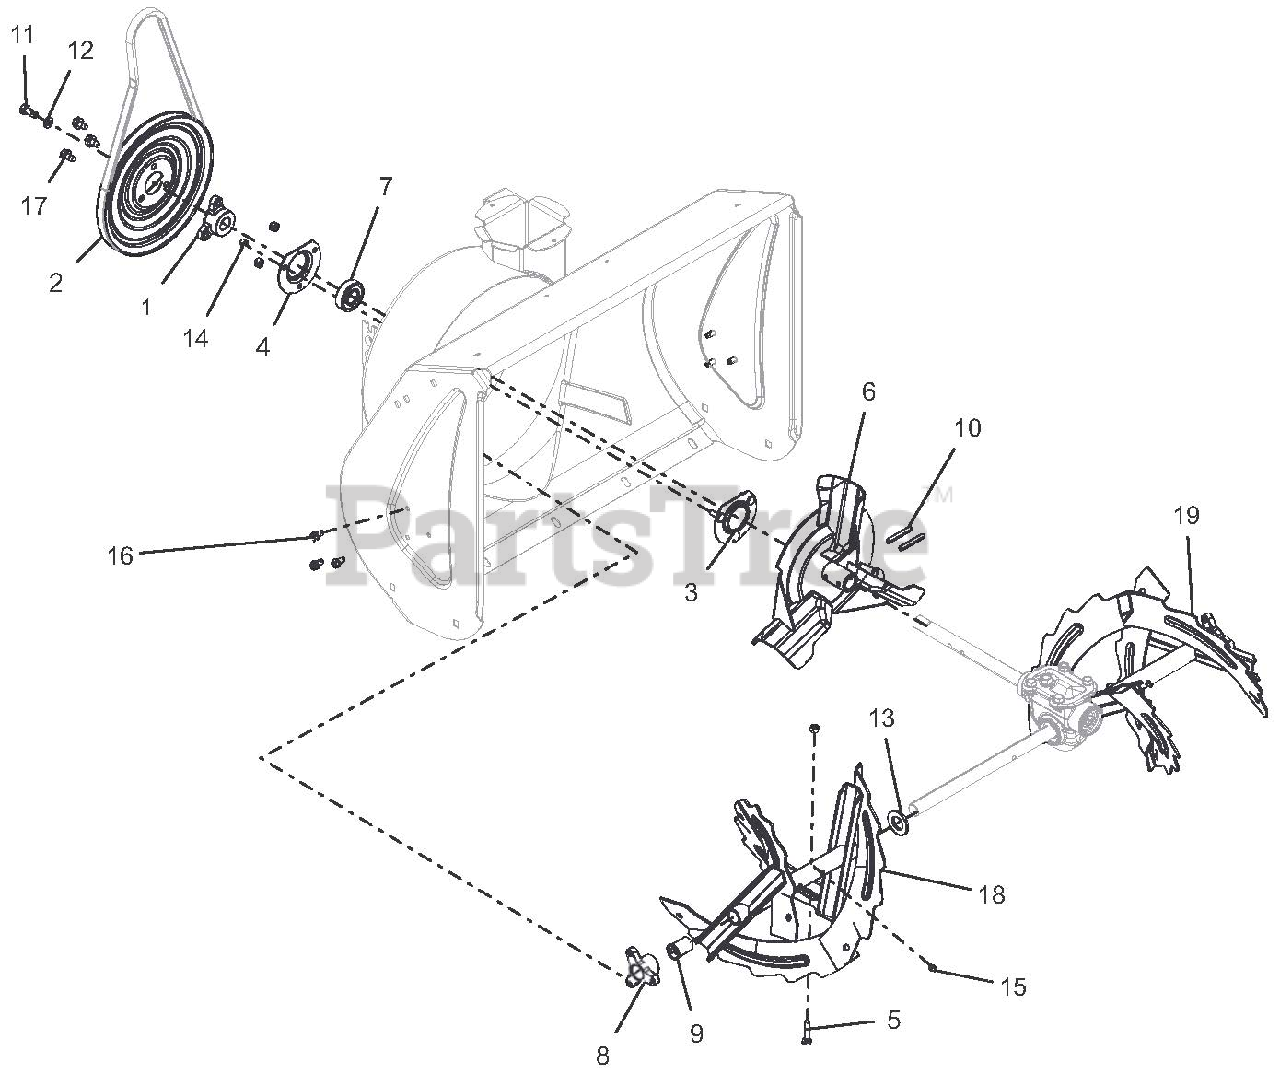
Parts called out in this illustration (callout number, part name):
1	PULLEY HUB, BOLT-ON D-BORE .75
2	PULLEY,SPIN FORM SINGLE GROOVE
3	BEARING FLANGE
4	BEARING FLANGE
5	SHEAR BOLT
6	IMPELLER, COMPACT 12" 3-BLADE
7	BRG-BALL .750X1.750X.50
8	BUSHING, RAKE SHAFT .75"
9	BSHG-FLG SPLIT NYLINER .75"ID
10	PIN-ROLL .250X1.75
11	BLT-HEX .31-24X.75 YWZC GR5
12	WSHR-LK .312X.097 HVY YWZC
13	@WSHR-FL-STL.812X1.50X.135YWZC
14	@NUT-LK-CTR .25-20 YWZC
15	ZERK,FITTING .25X.125 DRIVE IN
16	SCR-TAP .25-20X.50 HWH TR YWZ
17	@SCR-TAP .31-18X.50 HWH TR YWZ
18	RAKE, 24" RH, BLK SERR W/ZERK
19	RAKE, 24" LH, BLK SERR W/ZERK
